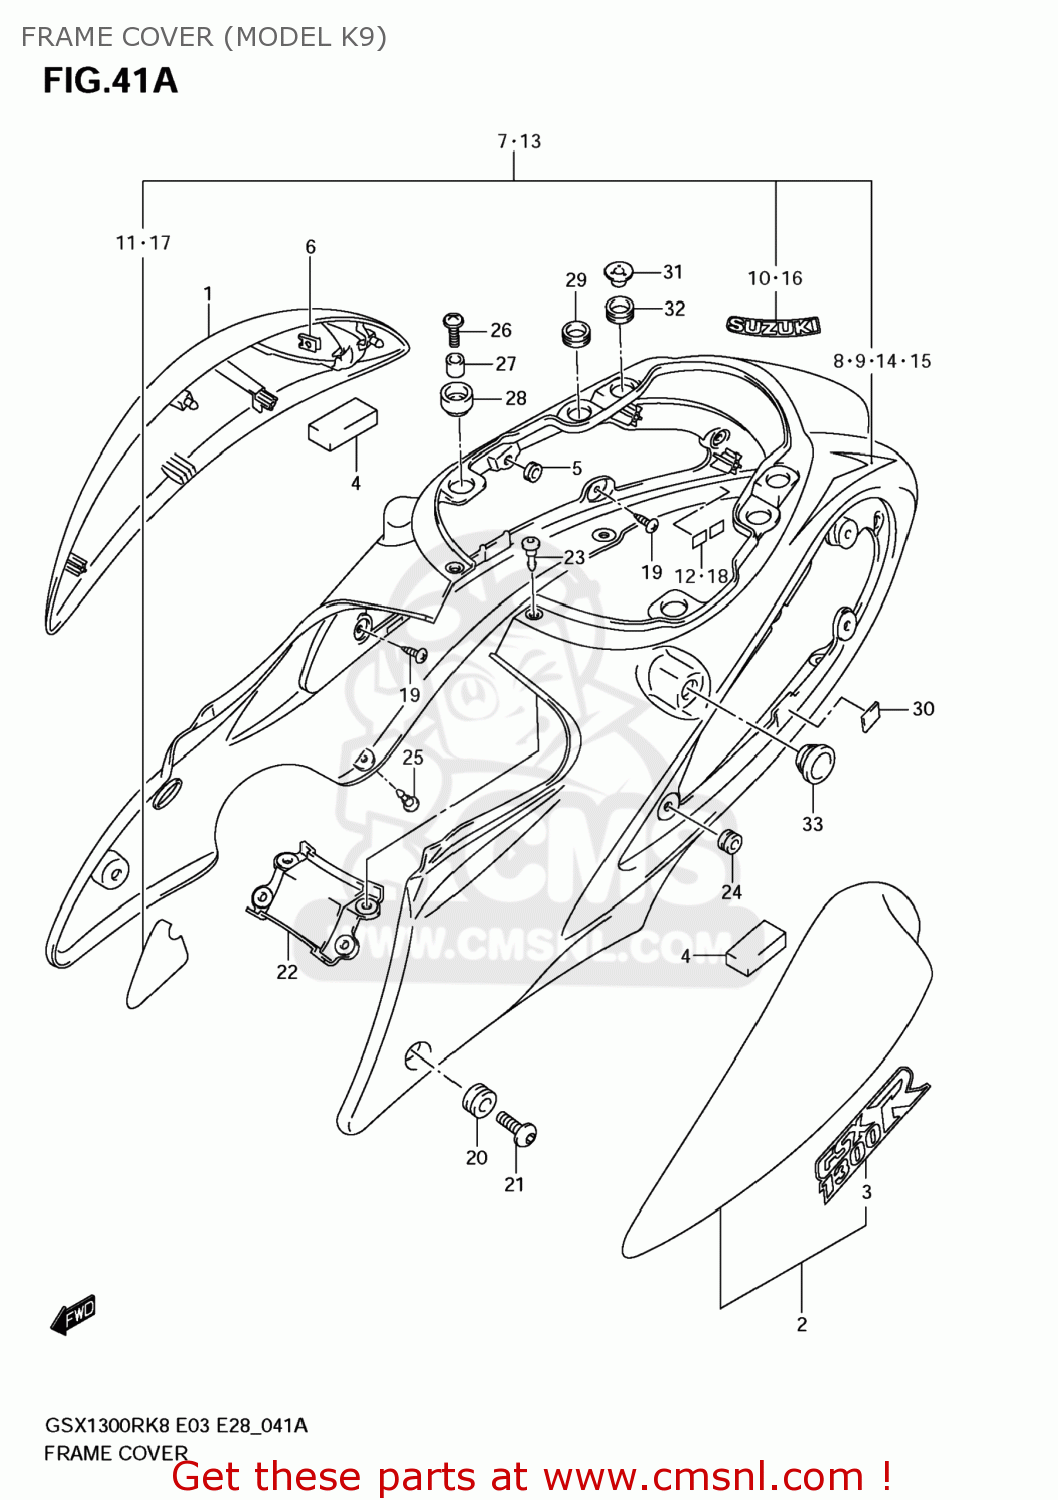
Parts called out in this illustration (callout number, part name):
1	COVER COMP,FRA
2	COVER COMP,FRA
3	EMBLEM,FRAME COVER
4	CUSHION,FRAME COVER
5	CUSHION
6	NUT
7	COVER,FRAME CTR
8	TAPE,COVER CTR,R
9	TAPE,COVER CTR,L
10	EMBLEM(GRAY)
11	TAPE,CTR
12	CUSHION,SEAT TAIL COVER LWR RR
13	COVER,FRAME CTR
14	TAPE,COVER CTR,R
15	TAPE,COVER CTR,L
16	EMBLEM(BLACK)
17	TAPE,CTR
18	CUSHION,SEAT TAIL COVER LWR RR
19	SCREW GSX1300R
20	CUSHION
21	SCREW(6X20)
22	LID,FRAME COVER CTR
23	CLIP(BLACK)
24	CUSHION
25	CLIP
26	SCREW(6X20)
27	SPACER(6.5X10X11)
28	CUSHION,SEAT TAIL COVER CTR
29	CUSHION,FRAME COVER UPR RR
30	PROTECTOR(170X95X3.0)
31	WASHER,FRAME COVER
32	CUSHION,FRAME COVER UPR RR RR
33	CUSHION,FRAME COVER CTR
